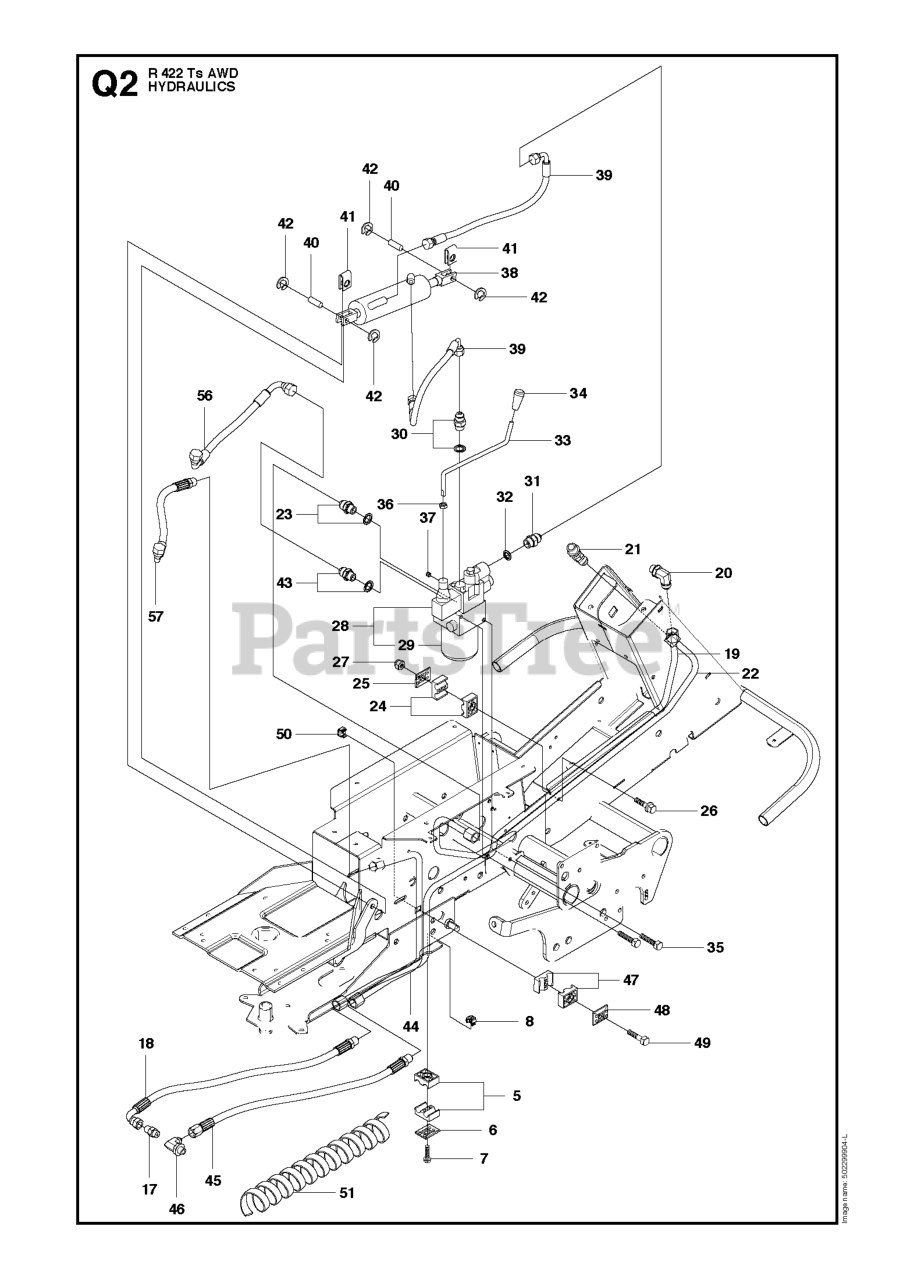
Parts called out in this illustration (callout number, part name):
5	PIPE CLAMP
6	COVER PLATE
7	SCREW EHHFM
24	PIPE CLAMP
27	LOCKNUT M6
29	FILTER
35	REPL BY 725 24 49-51
36	NUT
42	RETAINING RING SGA 10
47	PIPE CLAMP
51	HOSE GUARD
